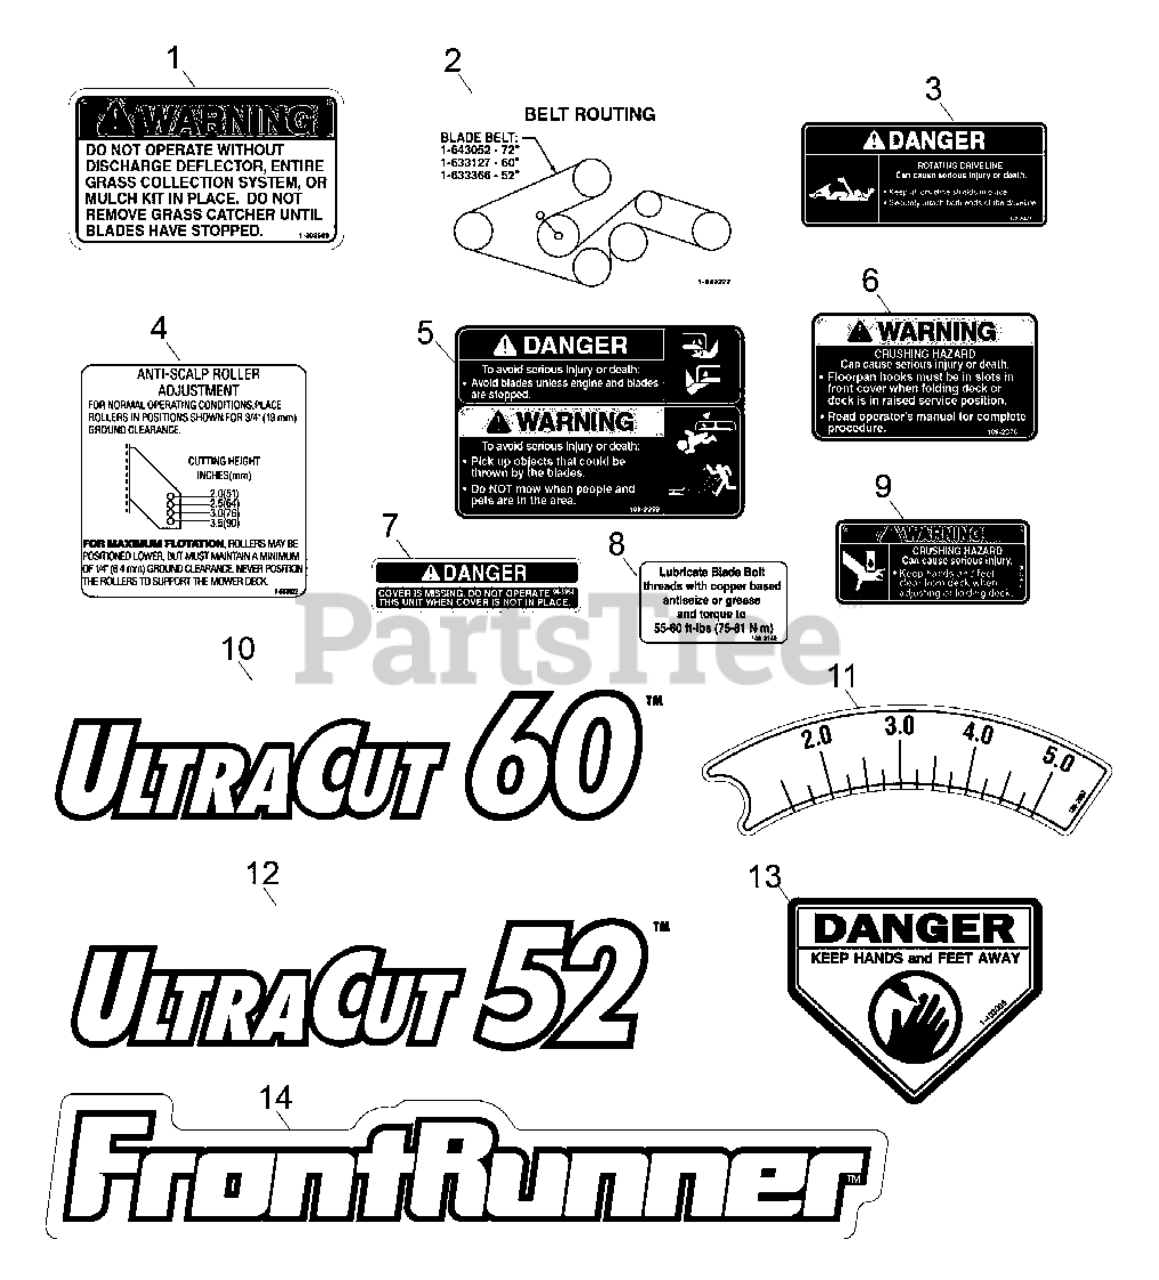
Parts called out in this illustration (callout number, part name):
1	DECAL-WARNING, DISCHARGE
2	DECAL,BELT ROUTING
3	DECAL-DRIVELINE
4	DECAL,ANTISCALP
5	DECAL,DECK WARNING
6	DECAL,CRUSHING HAZARD
7	DECAL-COVER, MISSING
8	DECAL,BOLT TORQUE
9	DECAL,CRUSHING HAZARD
10	DECAL,ULTRACUT 60
11	DECAL,DECK HEIGHT
12	DECAL,ULTRACUT 52
13	DECAL-DANGER
14	DECAL,FRONTRUNNER
